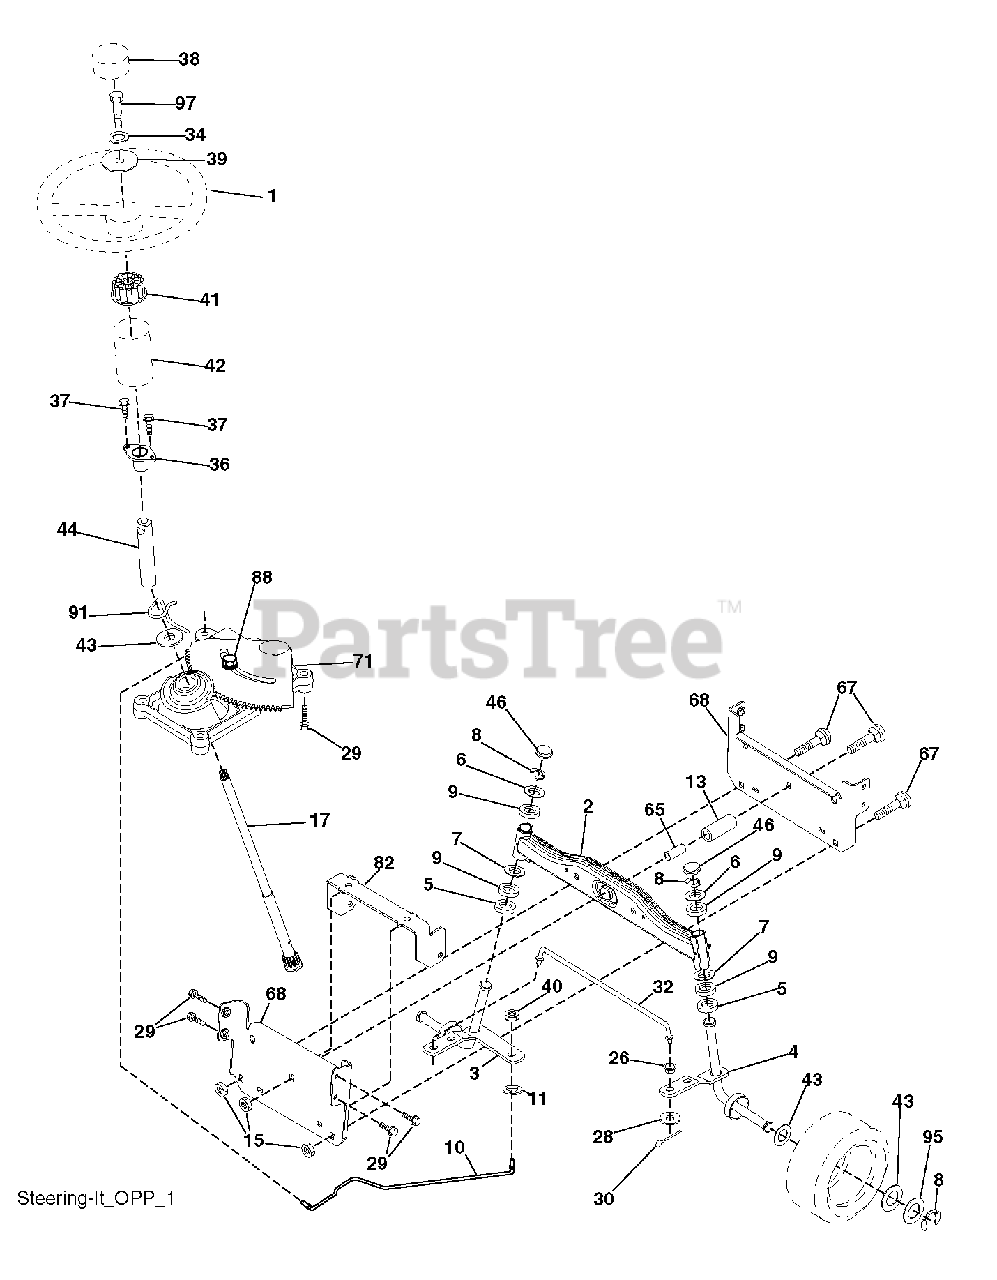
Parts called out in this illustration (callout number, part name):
1	WHEEL.STEERING.HARD.RIM.BLAC
2	AXLE HALF ASM-WELDED
3	SPINDLE.ASM.LH.15"TIRES
4	SPINDLE.ASM.RH.15"TIRES
9	BRNG T
10	DRAGLINK.15".TIRES.2001
11	WASHER, LOCK 3/8
13	TUBE, PIVOT AXLE
15	NUT LOCK FLG 3/8-16 UNC
17	SHAFT STEERING SPLINE
26	BUSHING.DRAGLINK
28	WASHER
29	SCREW, 3/8-16X3/4
30	COTTER PIN
32	ROD.TIE.WIRE.FORM
36	BUSHING, STEERING
38	INSERT, WHEEL STEERING
40	NUT CROWNLOCK 3/8-24
41	ADAPTER, WHEEL STNG..
42	BOOT.STEERING.SHAFT.BLACK
44	SHAFT.EXTEN.STRG.SPLINE
65	SPACER.BRACE.AXLE
67	BOLT CARRIAGE
68	BRACE.AXLE.15"TIRES
82	BRACKET.SUSP.CHASSIS.FRONT.15
88	BOLT, SHOULDER 7/16-20
91	CLIP.STEERING
95	WASHER.HARDENED
97	BOLT 5/16-18 X 4 W/PATCH
